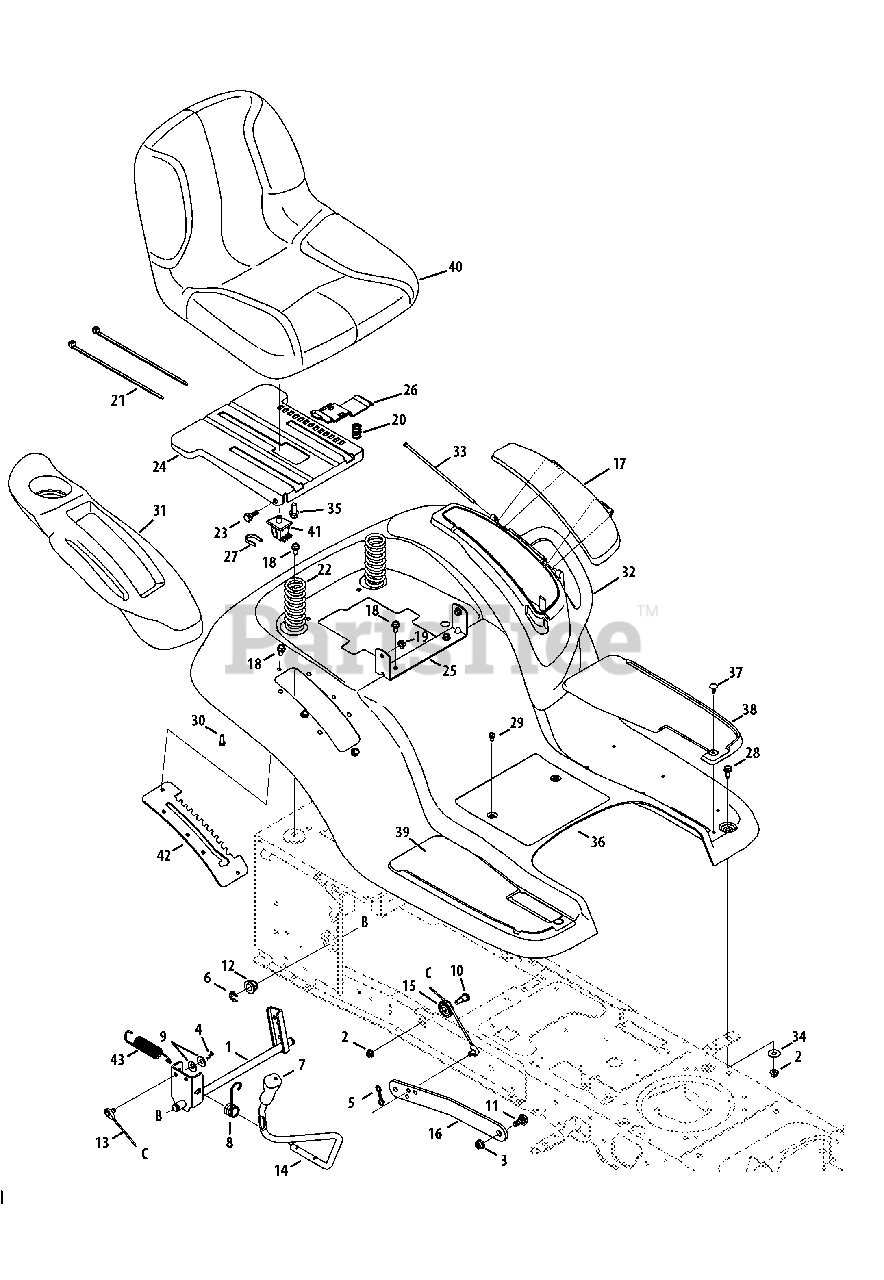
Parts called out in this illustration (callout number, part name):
1	Shaft Ass’y, Lift
2	Nut, Flange Lock, 5/16-18, Grf
3	Nut, Flange Lock, 3/8-16, Grf
4	Pin, Cotter, .072 Dia. x 1.13
5	Pin, Cotter, Bow-Tie 72
6	Ring, E Type, .625 Dia. Shaft
7	Grip, Handle, Cub, .50 ID
8	Spring, Torsion
9	Washer, Spring, .401 x .870 x .063
10	Screw, Shoulder, .437 x .470, 5/16-18
11	Bolt, Shoulder, .50, 3/8-16
12	Bearing, Hex Flange
13	Cable, Lift, 16.16
14	Handle, Lift
15	Pulley, Roller, Cable
17	Door, Cover, Fender
18	Screw, Self-tapping, 5/16-18, .750,
19	Nut, Flange Lock, 5/16-18, Gr5, Sd Lk
20	Spring, Compression, .68 x 1.065 x .055
21	Cable, Tie, 3/16 x .05 x 7.4
22	Spring, Compression, 1.50 x 3.90 x .200
23	Screw, Shoulder, .437 x .268, 5/16-18
24	Bracket, Mounting, Seat
25	Bracket, Pivot, Seat
26	Lever, Seat Adjustment
27	Clip, Retaining, Switch
28	Hex Screw, 5/16-18, .75, Gr5, Std
29	Screw, Self-tapping, 1/4-20, 0.500
30	Screw, HL, 1/4-15, 0.750
31	Cover, Fender, RH
32	Cover, Fender, LH
34	Washer, Flat .344 x 1.00 x .063
35	Hex Flange Bolt, 3/8/16, .875, Gr5
36	Fender, Cub Hydro
37	Clip, Ratchet, .250 Dia
38	Pad, Foot, LH
39	Pad, Foot, RH
40	Seat, High Back Cloth, Cub
41	Switch, Seat
42	Bracket, Lift
43	Spring, Extension, 1.15 OD x 5.99
